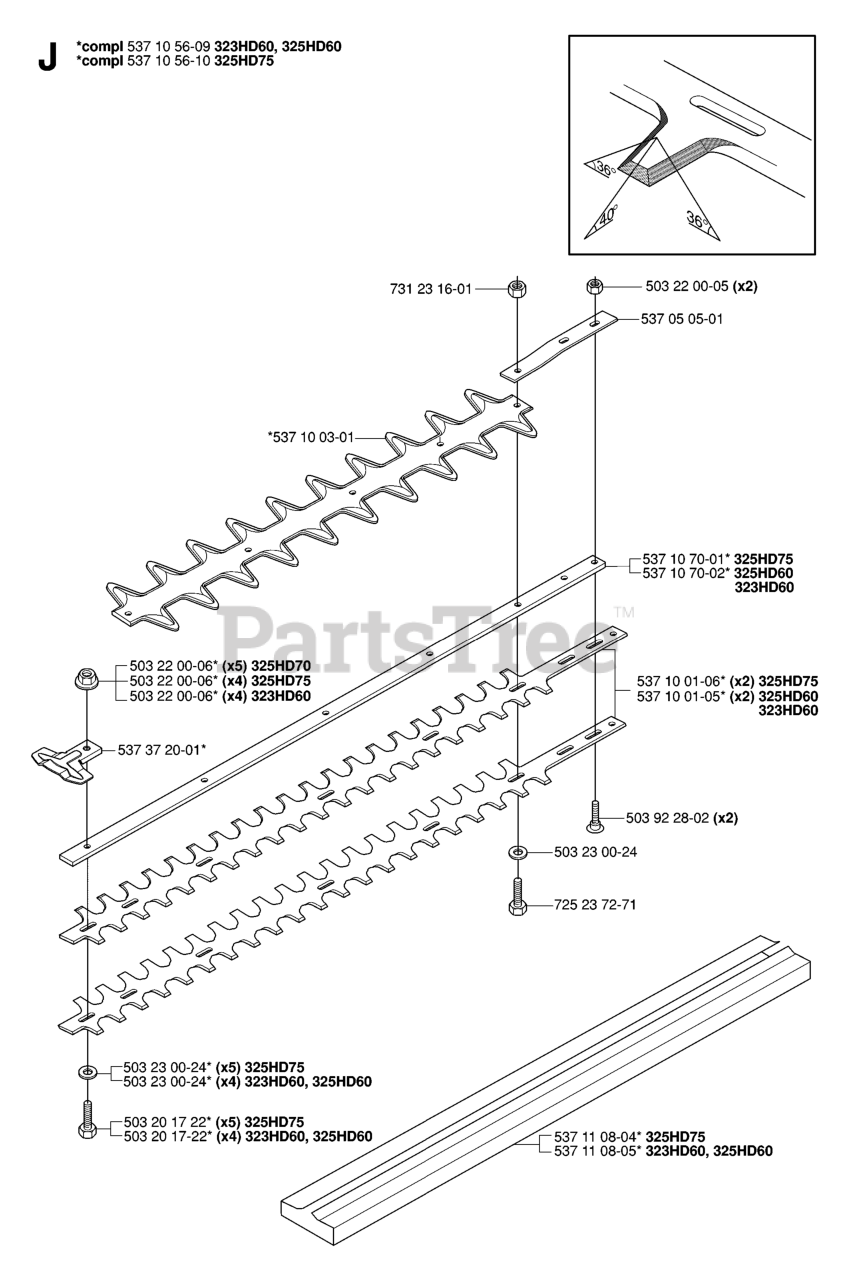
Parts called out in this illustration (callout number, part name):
1	CHUTE.WELDMENT.SNOW.ORANGE
2	DEFLECTOR.WELDMENT.PNT.ORANGE
3	RP.CONTROL.ASM.DEFLECTOR.SNOW
4	SEAL.DEFLECTOR
5	KNOB.OVERMOLD.DS.HUSQVARNA/BLK
6	RIVET BLIND
7	SCREW #10-24 X 5/8
8	SHIELD.SNOW.CHUTE
9	STRAP.SHEILD.RETAINER
15	RP CNTRL.HEAD.ASSEM.DEFLECTOR
16	RB SERVICE.CHUTE.DEF.CBL.BLK
17	ROD.GUARD.CHUTE (2 2)
18	NUT
19	SPRING.CHUTE.GUARD
